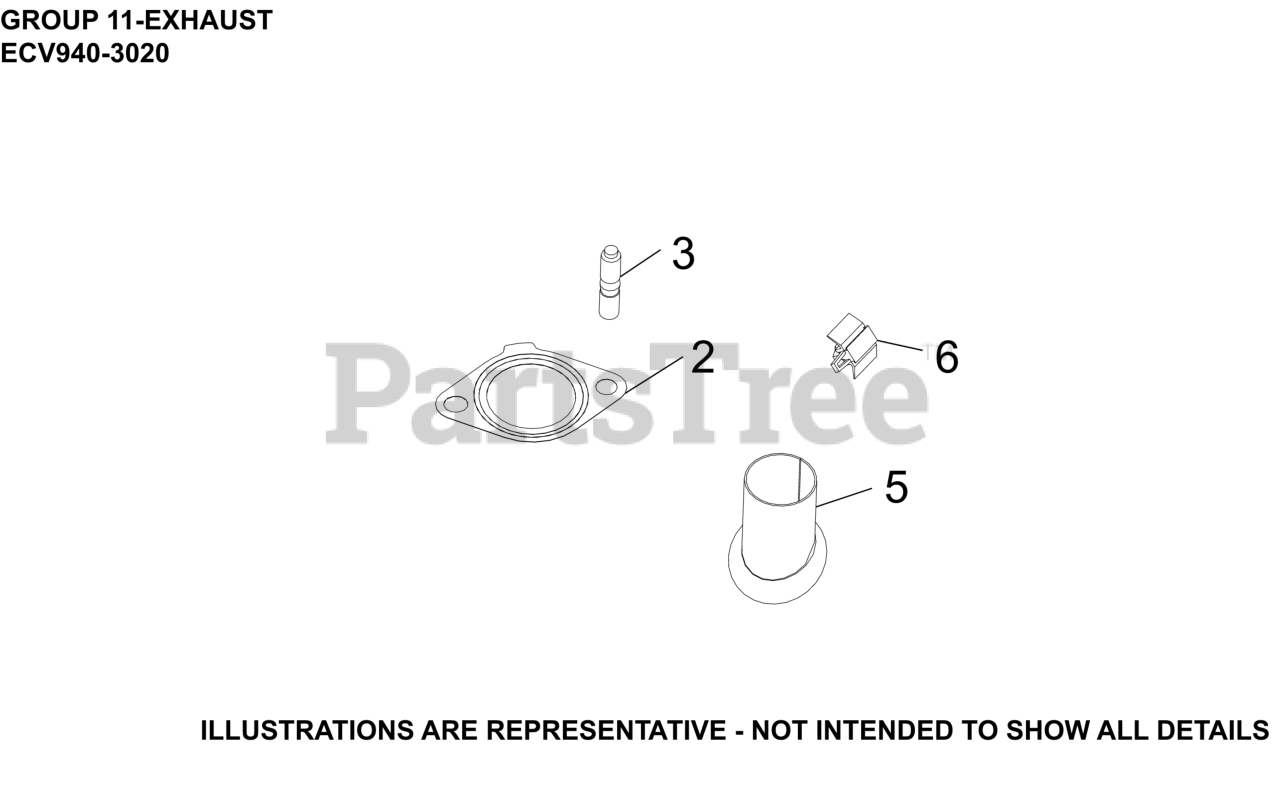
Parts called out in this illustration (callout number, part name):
2	GASKET, EXHAUST
3	STUD, METRIC EXHAUST
5	LINER, EXHAUST PORT
6	CLIP, O2 SENSOR
NI	KIT, O2 SENSOR
